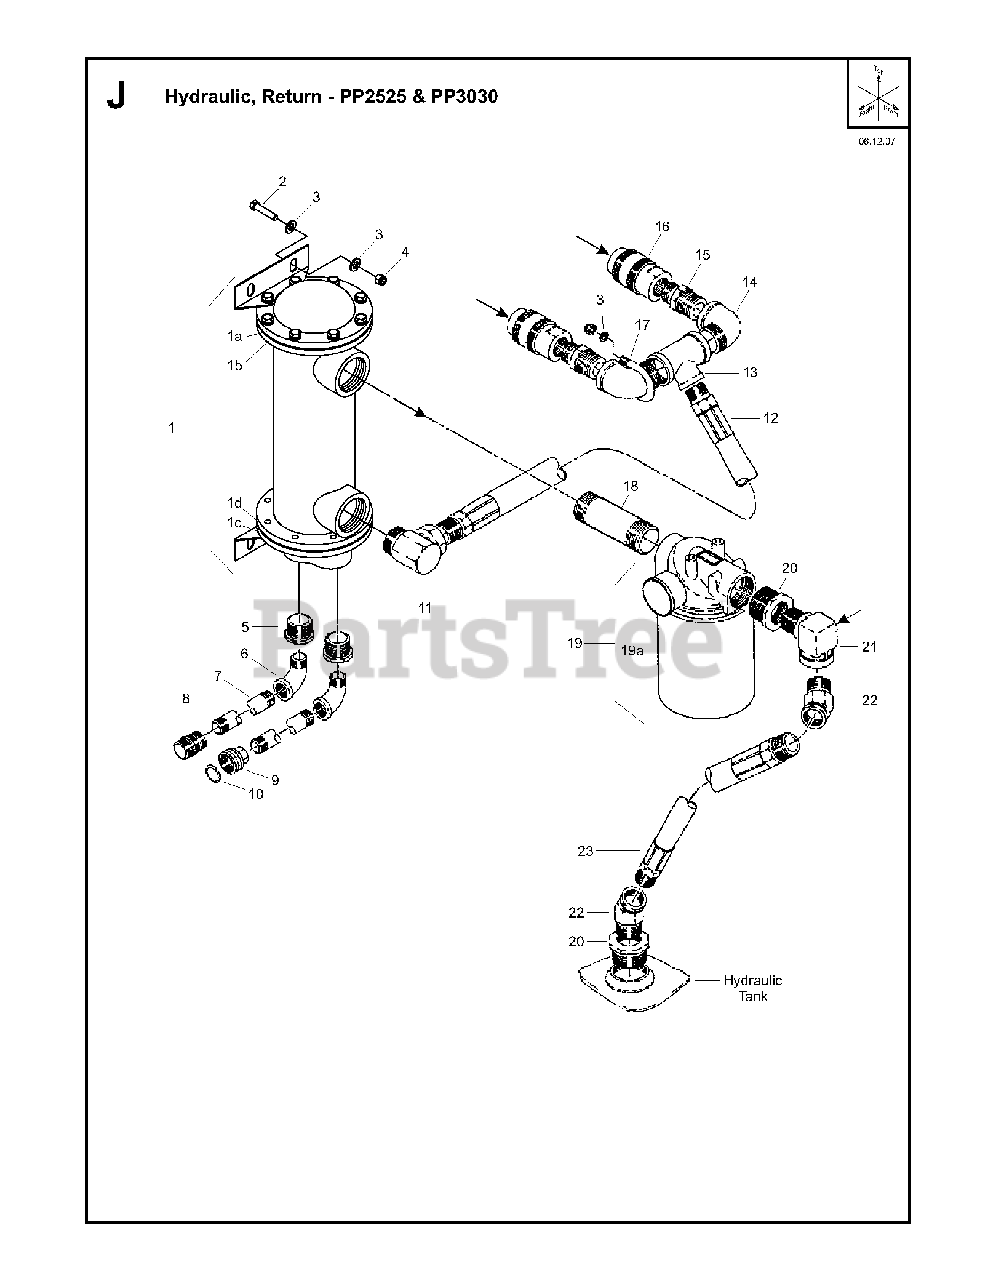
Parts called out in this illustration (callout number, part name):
2	SCREW
3	WASHER
4	NUT
